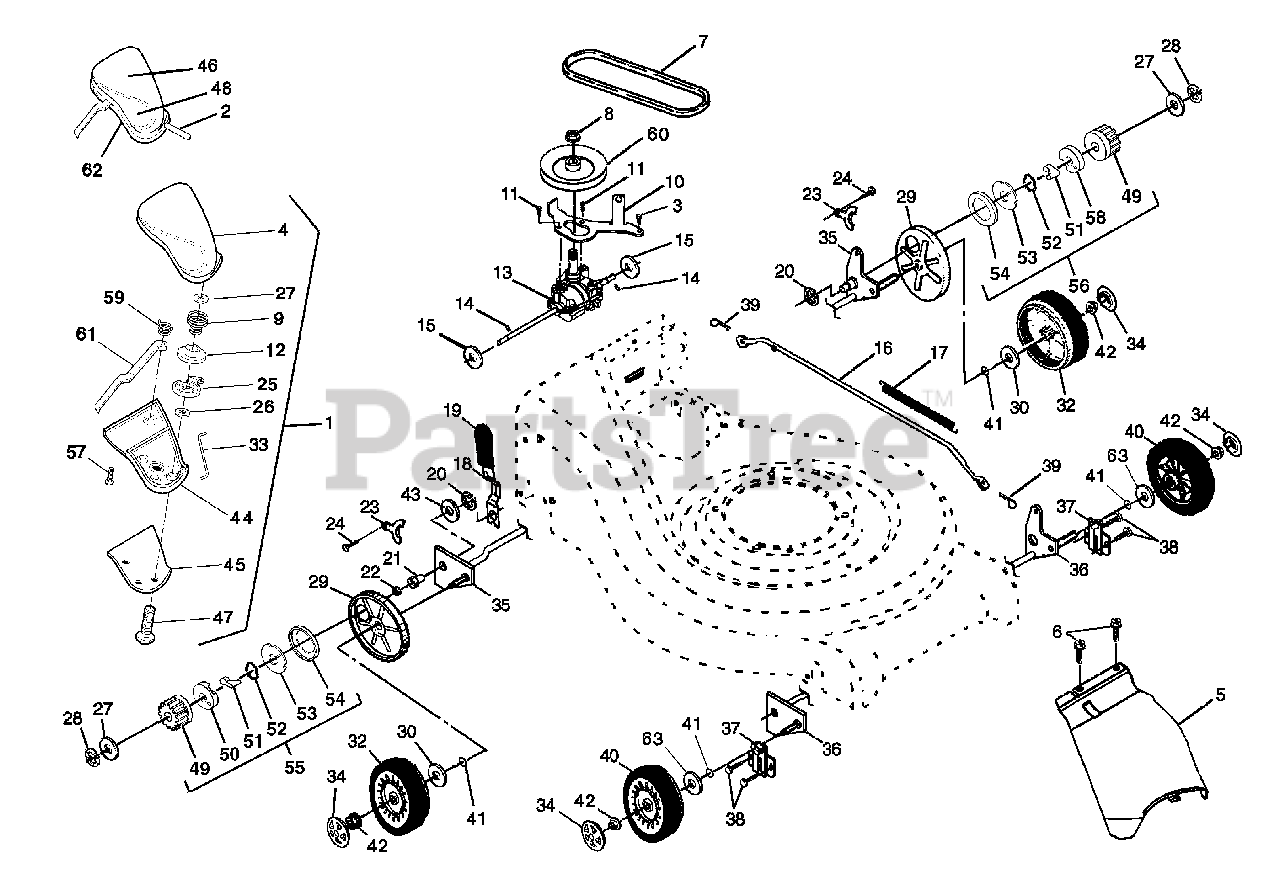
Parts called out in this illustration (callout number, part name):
1	Drive Control Assembly, Auto-Walk
2	Cable, Drive Control
4	Cover, Top, Auto-Walk Drive Control
5	Cover Drive
6	Screw, Threaded, Rolled #10-25 x .50
7	V-Belt
8	Nut, Hex, Flanglock, Zinc Plated 3/8-16
9	Spring, Pulley Adjuster
10	Belt Keeper Bracket
11	Screw, Hex Washer Head #10-24 x .668
12	Pulley, Split, Upper
13	Gear Case Assembly
14	Pin, Spring, Thrust
15	Washer, Hardened
16	Rod, Connecting
17	Spring, Extension
18	Spring Selector
19	Knob, Selector Spring
20	E-Ring 7/8
21	Bearing, Support
22	Bearing, Ball
23	Retainer, Drive Assembly, Stamped
24	Screw, Tapping, Hex Head 1/4-20 x .75
25	Pulley, Split, Lower
26	Pinion, Drive
28	E-Ring 7/16
29	Cover, Dust, Wheel
30	Washer 1/2 x 1-1/2 x .134
32	Wheel 9 x 2
33	Connector, Lever/Pulley
34	Hubcap
35	Shaft Assembly, Rear
36	Shaft Assembly, Front
37	Retainer, Front Shaft
38	Screw #12 x 5/8
39	Clip, Retainer
40	Wheel 8 x 2
41	O-Ring
42	Nut, Hex, Flangelock 3/8-16
44	Cover, Bottom, Auto-Walk Drive Control
45	Plate, Trigger, Auto-Walk Drive Control
46	Decal, Drive Control
47	Screw, Phillips Head #10 x 5/8
48	Decal, Drive Control Operation
49	Gear, Pinion
50	Retainer, Drive, RH
52	Spring, Torsion
53	Disc, Drive
54	Seal, Friction
55	Pinion/Pawl Assembly, RH
56	Pinion/Pawl Assembly, LH
57	Screw #8 x 3/4
58	Retainer, Drive, LH
59	Spring, Return, Lever
60	Pulley, Drive
61	Lever, Auto-Walk Drive Control
62	Decal, Drive Control Adjustment (bottom)
63	Washer, Flat 3/8
